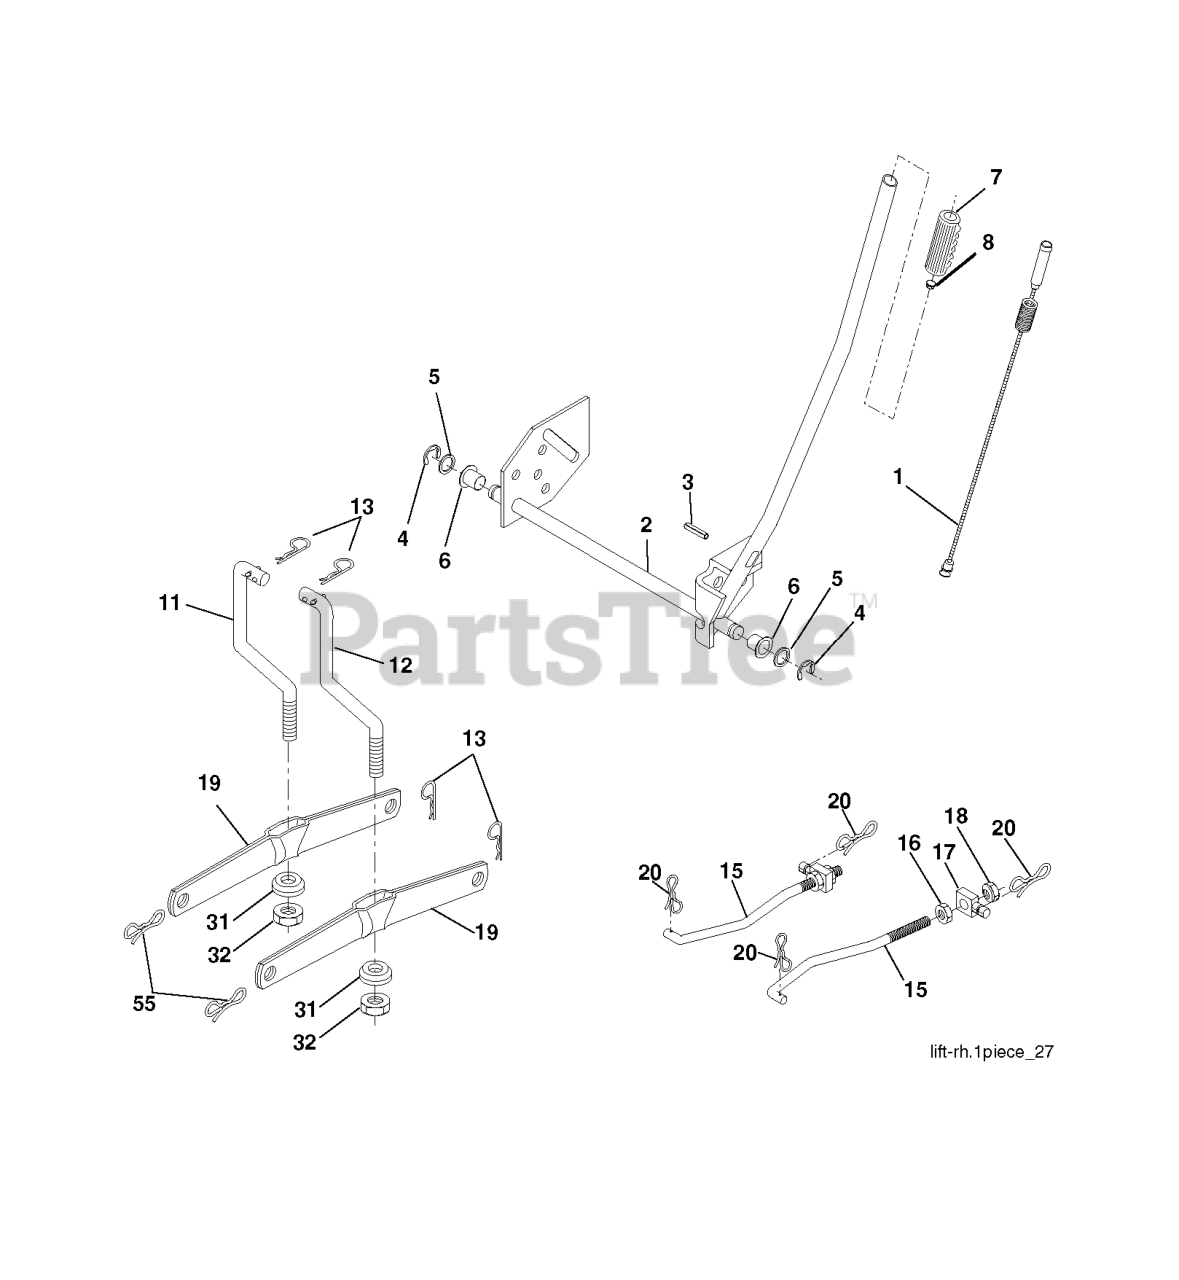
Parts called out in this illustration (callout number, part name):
1	WIRE ASM INNER W/ PLUNGER LT
2	SHAFT ASM R HANDLE
4	RETAINING RING LT
6	BEARING.NYLON
8	PLUNGER BUT KIT
11	LINK LIFT LH
12	LINK LIFT RH
13	RETAINER-SPRNG RB
15	LINK.SUSPENSION.FRONT
16	NUT.HEX.JAM.1/2-13
18	NUT.LK.W/WSH.1/2.
19	ARM.REAR.SUSPENSION
20	PIN.COTTER.7/16.BOW TI.
31	BEARING.PIVOT.LIFT
32	NUT CROWNLOCK 3/8-24
55	PIN.COTTER.5/16.BOW TI
